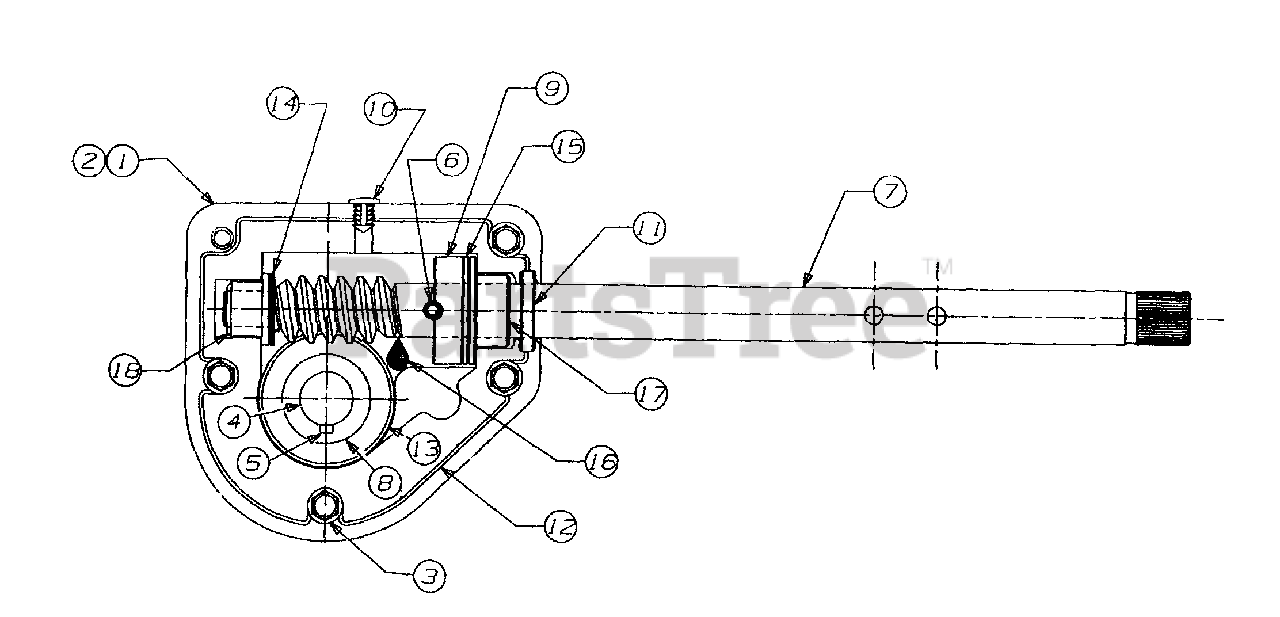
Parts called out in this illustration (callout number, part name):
1	Housing - L.H.
2	Housing - R.H.
3	Screw
4	Spiral Axle 22"
5	Key
6	Pin-Spiral
7	Shaft-Worm
8	Gear-Worm
9	Collar-Thrust
11	Seal-Oil
12	Locktite 5699
13	Washer-Flat
14	Washer-Flat
15	Washer-Flat
16	Grease (Ounce)
17	Bearing-Flange
18	Bearing-Flange
